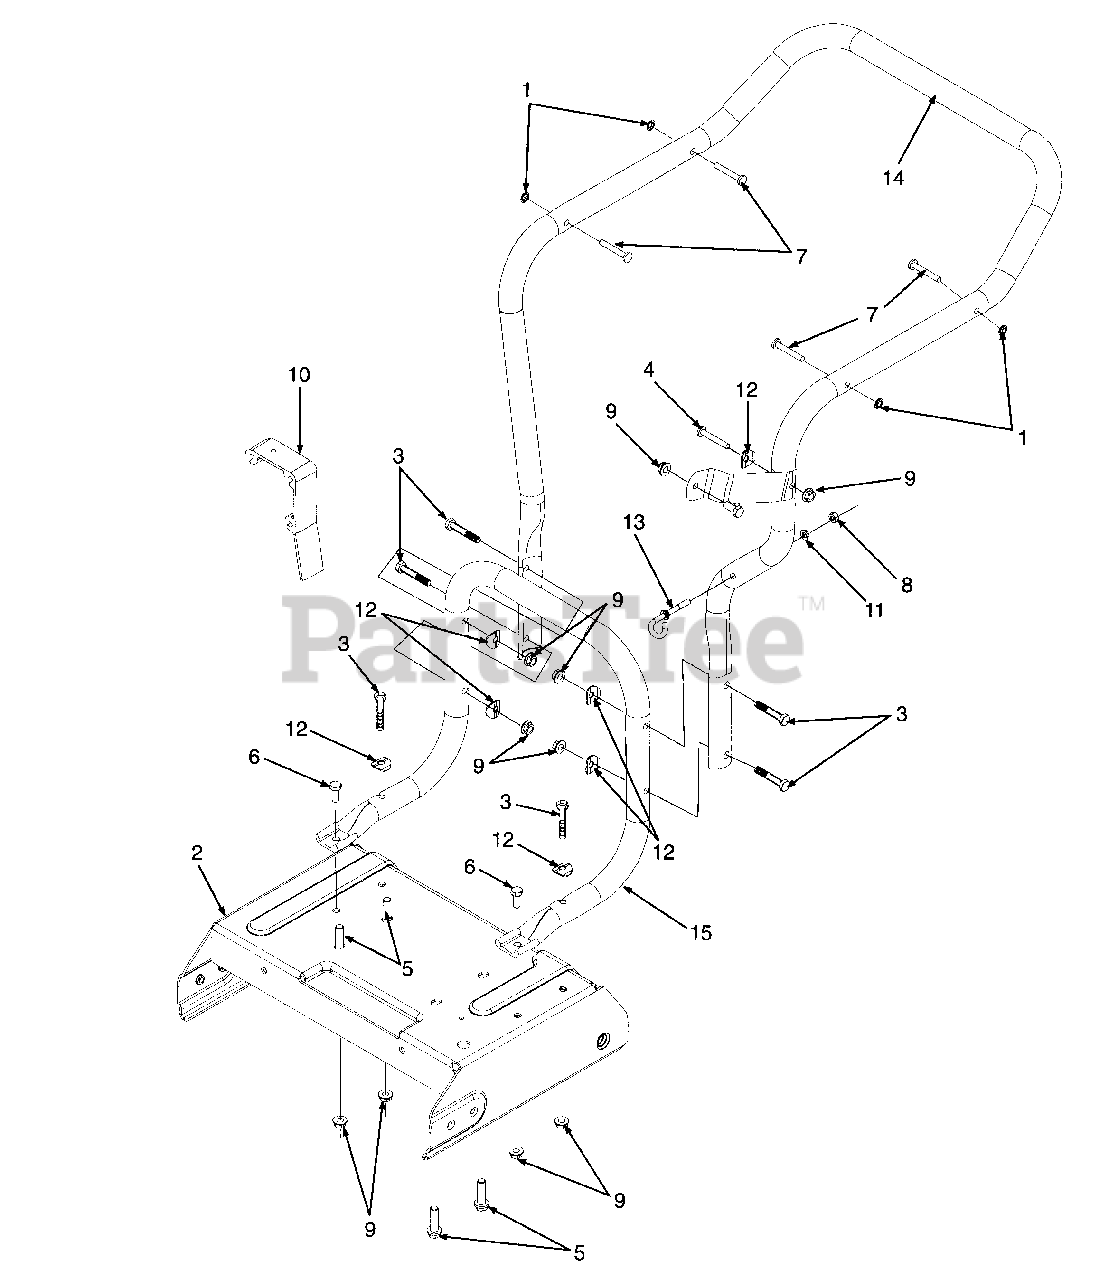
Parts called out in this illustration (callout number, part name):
1	PUSH NUT .250
4	HEX HEAD CAP SCREW 5/16-18 x 1.50
5	HEX LOCK WASH HD - TAP SCREW 3/8-16 x 1.25
6	HEX HEAD CAP SCREW 5/16-18 x .75
7	PIN: STUD .250 x 1.75
8	HEX NUT 1/4- 28
9	HEX FLANGE LOCK NUT 5/16-18
10	MOUNTING ADAPTER
11	LOCK WASHER 1/4
12	SADDLE WASHER .320 ID x .83 OD
13	EYE BOLT
